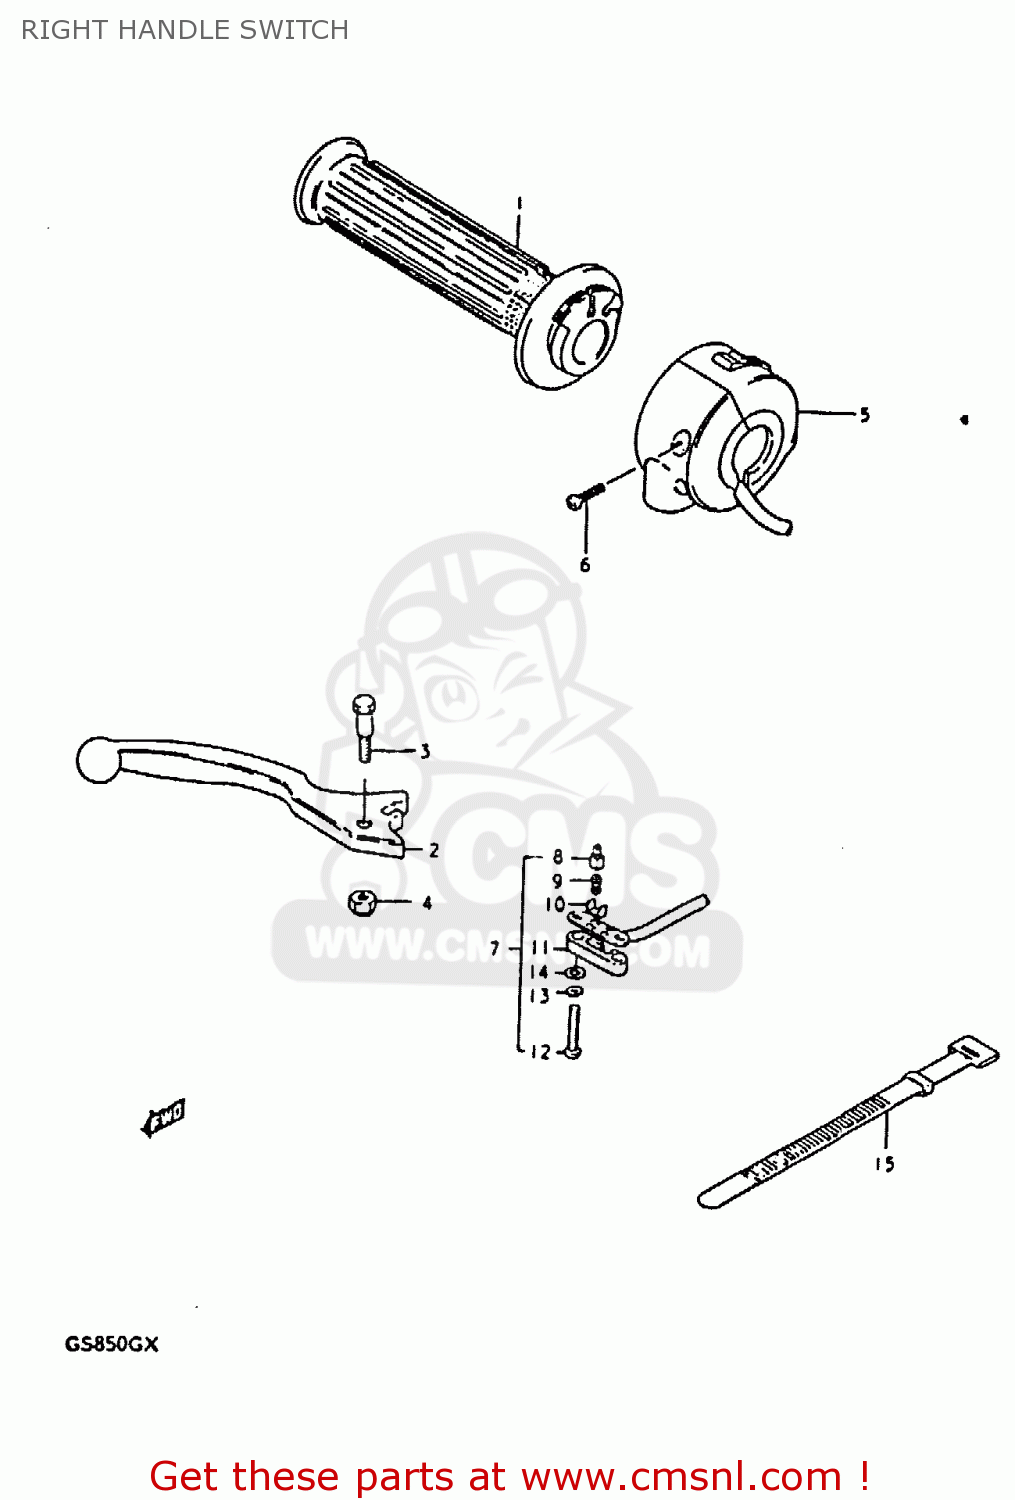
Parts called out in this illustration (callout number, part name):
1	GRIP,THROTTLE
2	LEVER,BRAKE
3	BOLT
4	NUT 6MM
5	SWITCH ASSEMBLY,HANDLE,RIGHT
6	SCREW
15	CLAMP(L:120)
